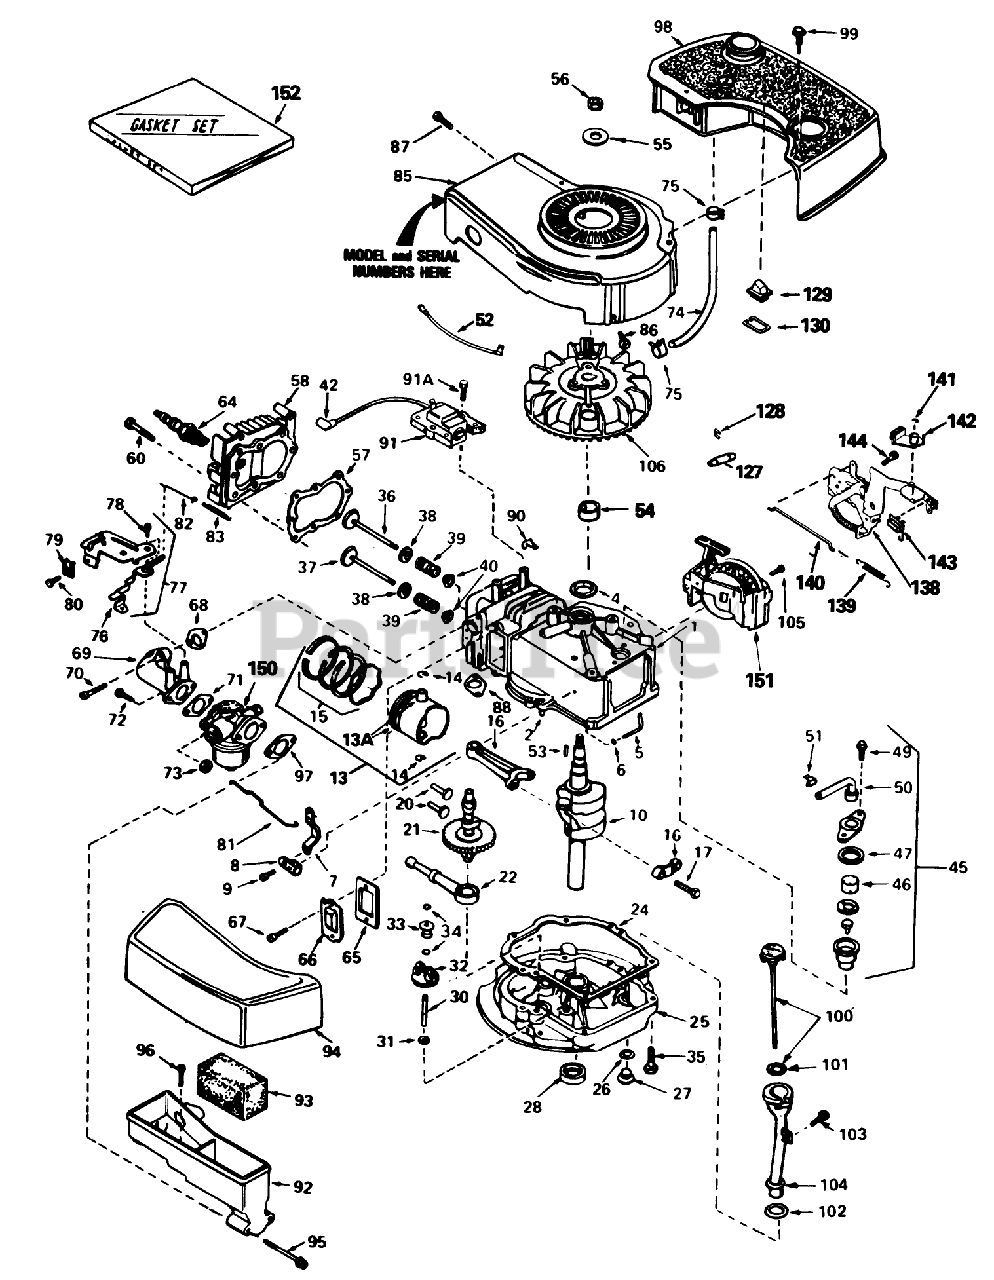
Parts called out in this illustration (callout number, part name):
1	Cylinder Assy. (Inc. #2 4)
2	Pin-Dowel
4	Seal-Oil
5	Rod, Governor (Incl. No. 36)
6	Washer-Flat
7	Governor Lever
8	Clamp-Lever, Governor
9	Screw
10	Crankshaft
13	Piston, Pin Ring Assy. (Std.) (Incl. Ref. #13A, 14 15)
13	Piston, Pin Ring Assy. (.010 oversize) (Incl. Ref. #13A, 14 15)
13	Piston, Pin Ring Assy. (.020 oversize) (Incl. Ref. #13A, 14 15)
13A	Piston Pin Assy. (Incl . Ref. . #14) (Std.)
13A	Piston Pin Assy. (Incl. Ref. #14) (.010 Oversize)
13A	Piston Pin Assy. (.020 oversize) (Incl. Ref. #14)
14	Ring-Retaining, Piston Pin
15	Ring Set (Std.)
15	Ring Set (.020" OS)
15	Ring Set (.010" OS)
16	Rod Assy., Connecting (Incl. Ref. #17)
17	Bolt-Rod, Connecting
20	Lifter-Valve
21	Camshaft(Mech.Comp. Release)
22	Oil Pump ASM
24	Gasket, Mounting
25	Flange Assy., Mounting (Incl. Ref. #26thru 30)
26	Gasket-Oil Drain
27	Plug Oil Drain
28	Seal Oil
30	Shaft-Governor
31	Washer-Flat
32	Governor Gear ASM
33	Spool-Governor
34	Ring-Retaining
35	Screw (1/4-20 x 1-1/4)
36	Valve, Intake (Std.) (Incl. Ref. #40)
36	Valve, Intake (1/32" oversize)(Incl. No. 40)
37	Valve, Exhaust (Std.)(Incl. No. 40)
37	Valve, Intake (1/32" oversize)(Incl. No. 40)
38	Cap-Upper Valve Spring
39	Spring-Valve
40	Cap-Valve, Spring
42	Cover-Spark Plug
45	Breather Assy. (Incl. Ref. #46 thru 51)
46	Element-Breather
47	Gasket-Breather
49	Screw (10-24 x 9/16)
50	Tube, Breaker
51	Clip, Breather
52	Ground Wire
53	Key-Flywheel
54	Spacer
55	Washer-Belleville
56	Nut-Flywheel
57	63573 GIL 42 SNWTHW
58	Head-Cylinder
60	Screw (5/16-18x1-1/2)
64	Plug, Spark (J17LM or equiv.)
64	Plug, Spark (Champion RCJ-8)
65	Gasket-Breather
66	Cover-Valve
67	Screw
68	Gasket-Intake
69	Pipe, Intake (Incl. No. 68)
70	Screw (1/4-20 x 1)
71	Gasket-Carburetor
73	Nut and Lock Washer (1/4-28)
74	Line-Fuel
75	Clamp-Line, Fuel
76	Lever Control
77	Control Assy., Speed (Incl. Nos, 76, 78 89)
78	Screw, Hex Washer Hd Shoulder Self-Tap
79	Conduit
80	Screw (10-32 x 3/8)
81	Link-Throttle
82	Link Governor Spring
83	Spring Governor
85	Housing-Blower
86	Screw (1/4-20x19/32)
87	Screw (10-24 x 9/16)
88	Gasket Exhaust
90	Clip-Wire
91	Solid State
91A	Screw
92	Body Air Cleaner
93	Filer, Air
94	Cove, Air Cleaner
95	Screw Fil Hd.
96	Screw, Hex Hd.
97	Gasket-Air Cleaner
98	Tank, Fuel
99	Screw (10-32 x 35/64)
100	Dipstick, Oil (Incl. Ref. #101)(Twist Lock)
101	O-Ring
102	Gasket
103	Screw (10-32 x 1/2)
104	Tube-Oil Fill
105	Screw (1/2-20x5/8)
106	Flywheel
127	Coupling, Starter Rope
128	Staple, Rope Retainer (Strip of 25 Pieces)
129	Pulley Assy., Starter
130	Retainer, Pulley
138	Bracket Assy.
139	Spring-Extension
140	Link-Control
141	Ring-Retaining
142	Lever-Brake
143	Terminal
144	Screw-Hex. Hd.
150	Carburetor (Incl. Ref. #71)
151	Starter, Sidemount rewind
152	Gasket Set
